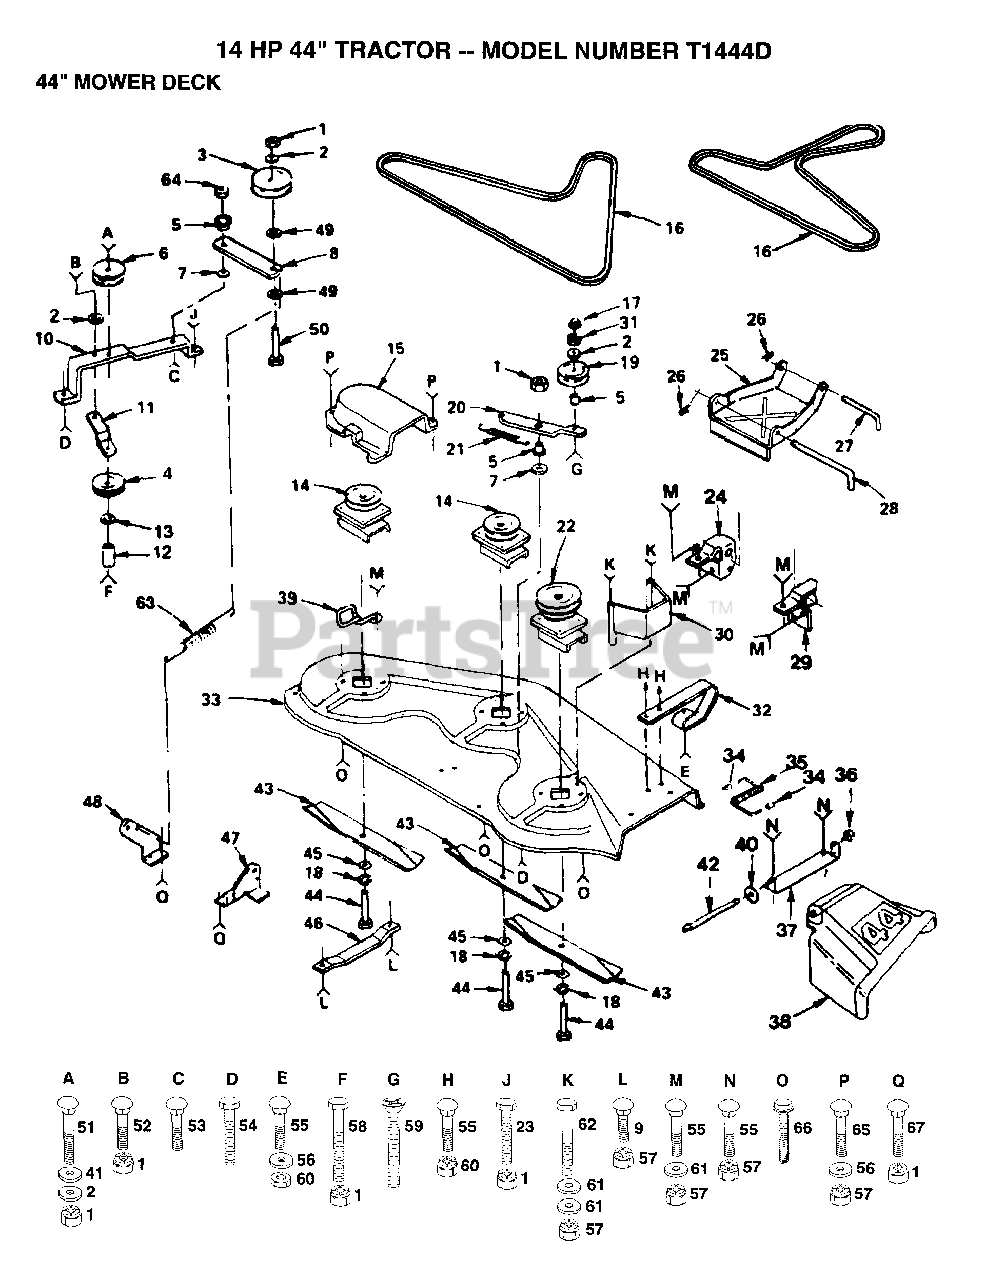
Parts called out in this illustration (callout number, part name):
2	WASHER
3	PULLEY IDLER
4	IDLER-FLAT T
5	SPACER RETAINER
6	IDLER-INSIDE T
7	"WASHER, WEAR LT"
8	ARM IDLER
9	BOLT
10	"SUPPORT YT, BAR"
11	BRACE-IDLER YT
12	SPACER
13	WASHER
15	GUARD YT
16	BELT-V.79.1.MWR
17	NUT.HEX.3/8-16UNC
19	IDLER.FLAT.GTV
20	ARM-IDLER YT
22	MANDREL PRIMARY
23	BOLT
24	BRACKET LH YT
25	"STOP, LINK PARAL"
26	SPRING.RETAINER
27	"ROD, FRT. PARAL T"
28	HINGE PIN T
29	BRACKET RH YT
30	GUARD BELT HYT
31	LOCKWASHER
32	RUNNER.RH
34	CAP-SLEEVE LT
35	SPRING TORSION
36	NUT PUSH M
38	DEFLECTOR SHIELD
39	BELT RETIANER
40	WASHER
41	WASHER
42	ROD-HINGE T
44	BOLT.3/8-24X1-1/2
45	WASHER
46	RUNNER-LH M
47	BRKT SUSP REAR RH
48	BRKT SUSP REAR LH
49	WASHER
50	BOLT
51	BOLT
53	BOLT
55	BOLT
56	WASHER
58	BOLT - HEX 3/8 - 16 X 3
59	SCREW YT
61	WASHER M
62	BOLT
63	"SPRING.EXT.8.5"""
64	LOCKNUT
66	SCREW
67	BOLT
